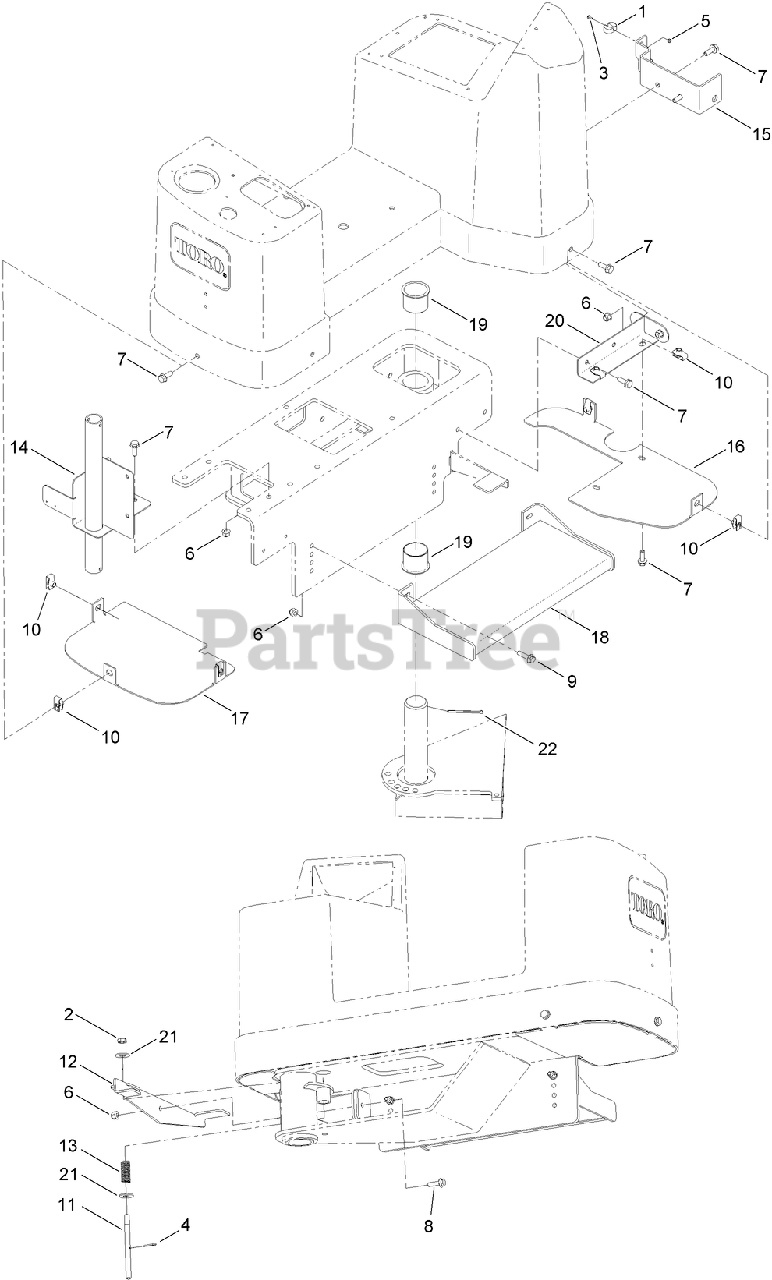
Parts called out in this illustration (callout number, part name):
1	CLIP-SPRING
2	NUT-JAM
3	SCREW-PRH
4	PIN-COTTER
5	NUT-KEPS
6	NUT-LOCK, NI
7	SCREW-HHF
8	SCREW-HHF
9	SCREW-HHF
11	ROD-SWING, SEAT
12	ARM-ADJUSTMENT, SEAT
13	SPRING-PIVOT LOCK, SEAT
14	MOUNT-UMBRELLA
15	PLATE-RETAINING, CORD
16	PLATE-GUARD, SPLASH
17	PLATE-GUARD, SPLASH
19	BEARING-FLANGED
20	SUPPORT-SHROUD, LEFT
21	WASHER-FLAT
22	PIN-COTTER
